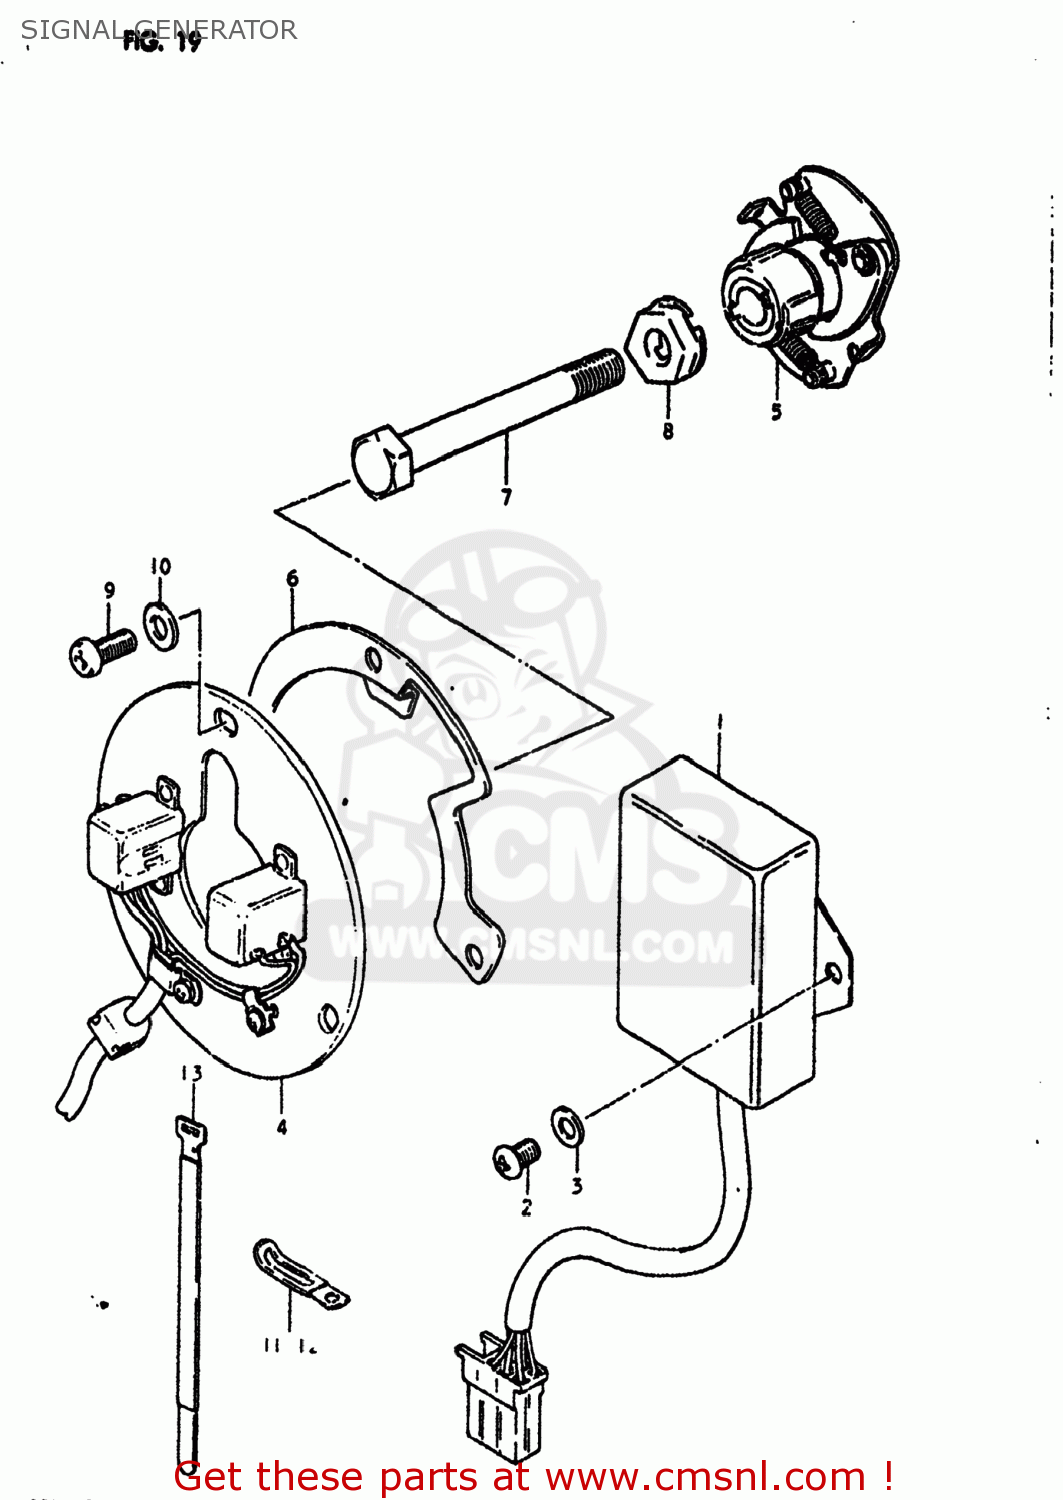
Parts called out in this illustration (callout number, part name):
1	CDI UNIT KOKUSAN
2	SCREW
3	WASHER
4	SIGNAL GENERATOR ASSEMBLY
5	GOVERNOR ASSEMBLY
6	PLATE,IGNITION TIMING
7	BOLT
8	WASHER
9	SCREW(5X12)
10	WASHER
11	CLAMP L:35
12	CLAMP L:35
13	CLAMP
